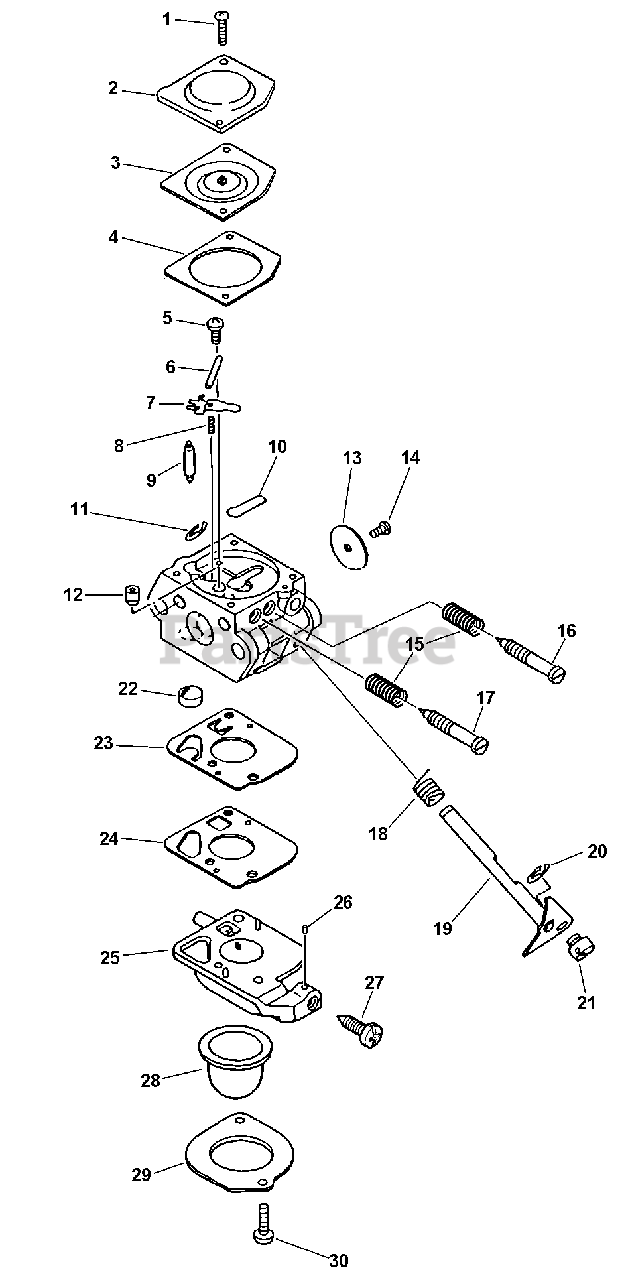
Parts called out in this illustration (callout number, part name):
2	Cover, Diaphragm
3	Diaphragm
4	Gasket, Diaphragm
7	Arm, Valve
8	Spring, Coil
9	Valve, Needle
10	Plug, Welch
12	Nozzle, Check Valve
13	Valve, Throttle
15	Spring, Coil
16	Needle, High Speed
17	Needle, Idle
18	Spring, Throttle Return
19	Shaft, Throttle
22	Strainer
23	Diaphragm, Fuel Pump
24	Gasket, Fuel Pump
25	Cover, Pump
26	Piece, Friction
27	Screw, Idle Adjust
28	Pump, Primer
